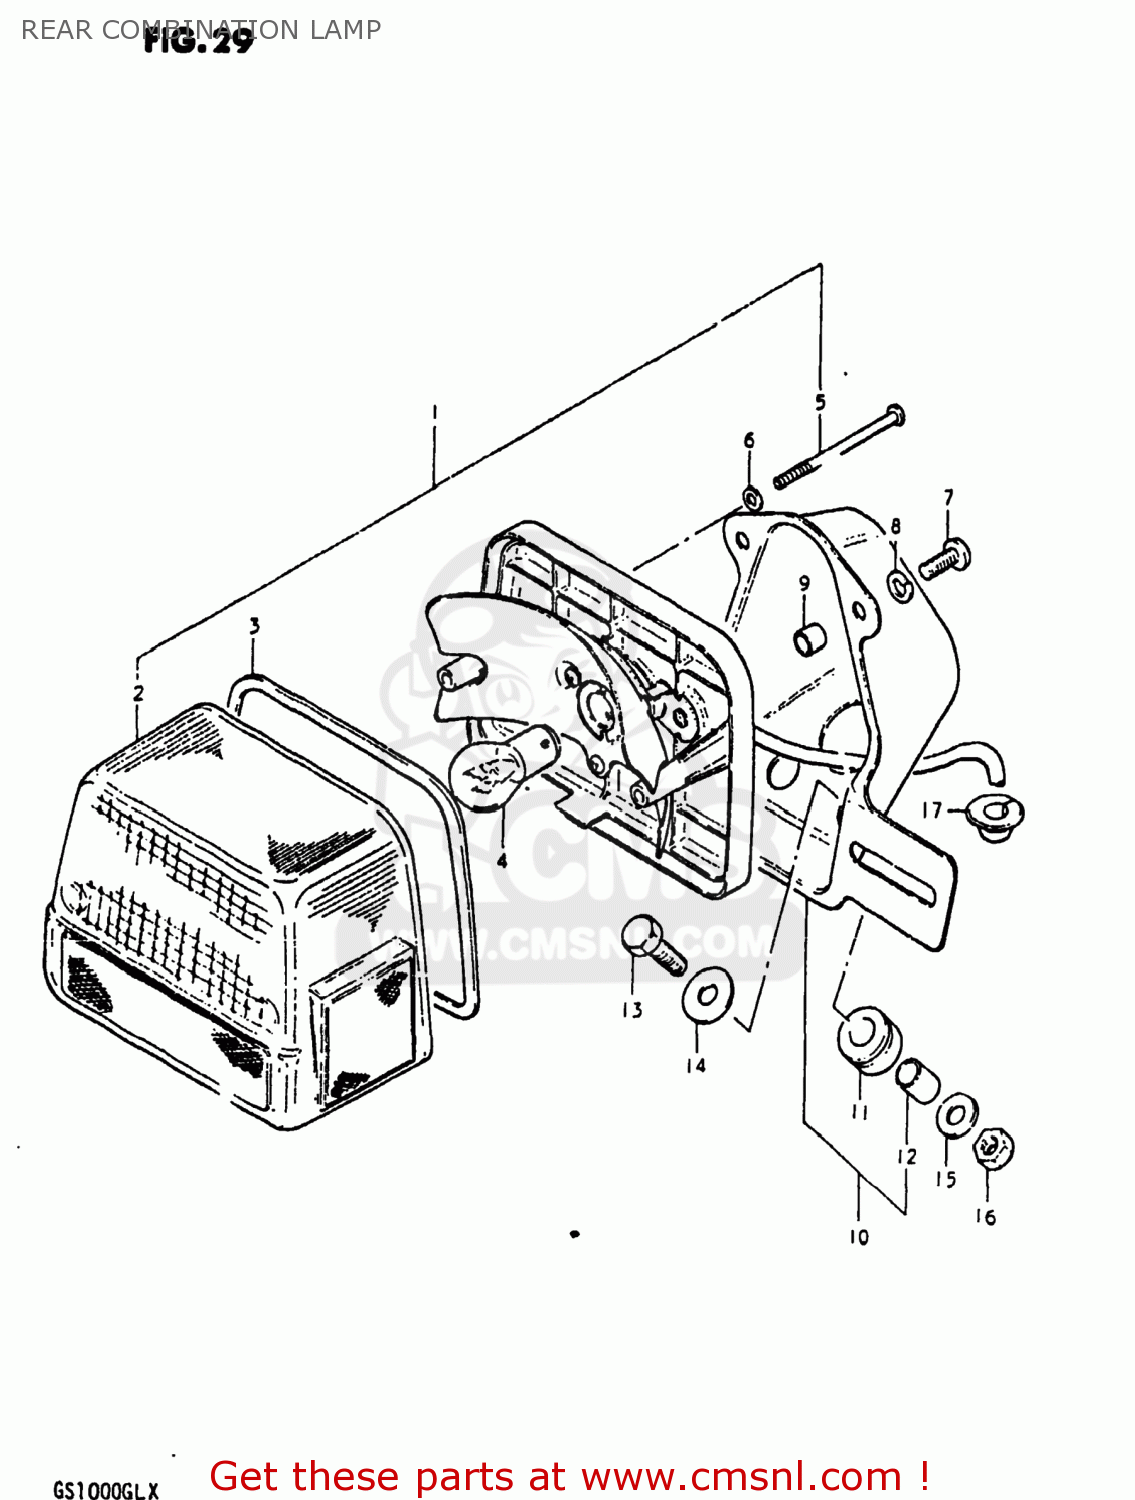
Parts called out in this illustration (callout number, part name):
1	LAMP UNIT,REAR COMBINATION
2	LENS
3	GASKET (NAS)
4	BULB(12V23W)
5	SCREW
6	GASKET (NAS)
7	SCREW
8	LOCK WASHER
9	SPACER
10	BRACKET UNIT,TAIL LAMP
11	CUSHION
12	SPACER
13	BOLT
14	WASHER (6.5X20X1.2)
15	WASHER
16	NUT
17	GROMMET
